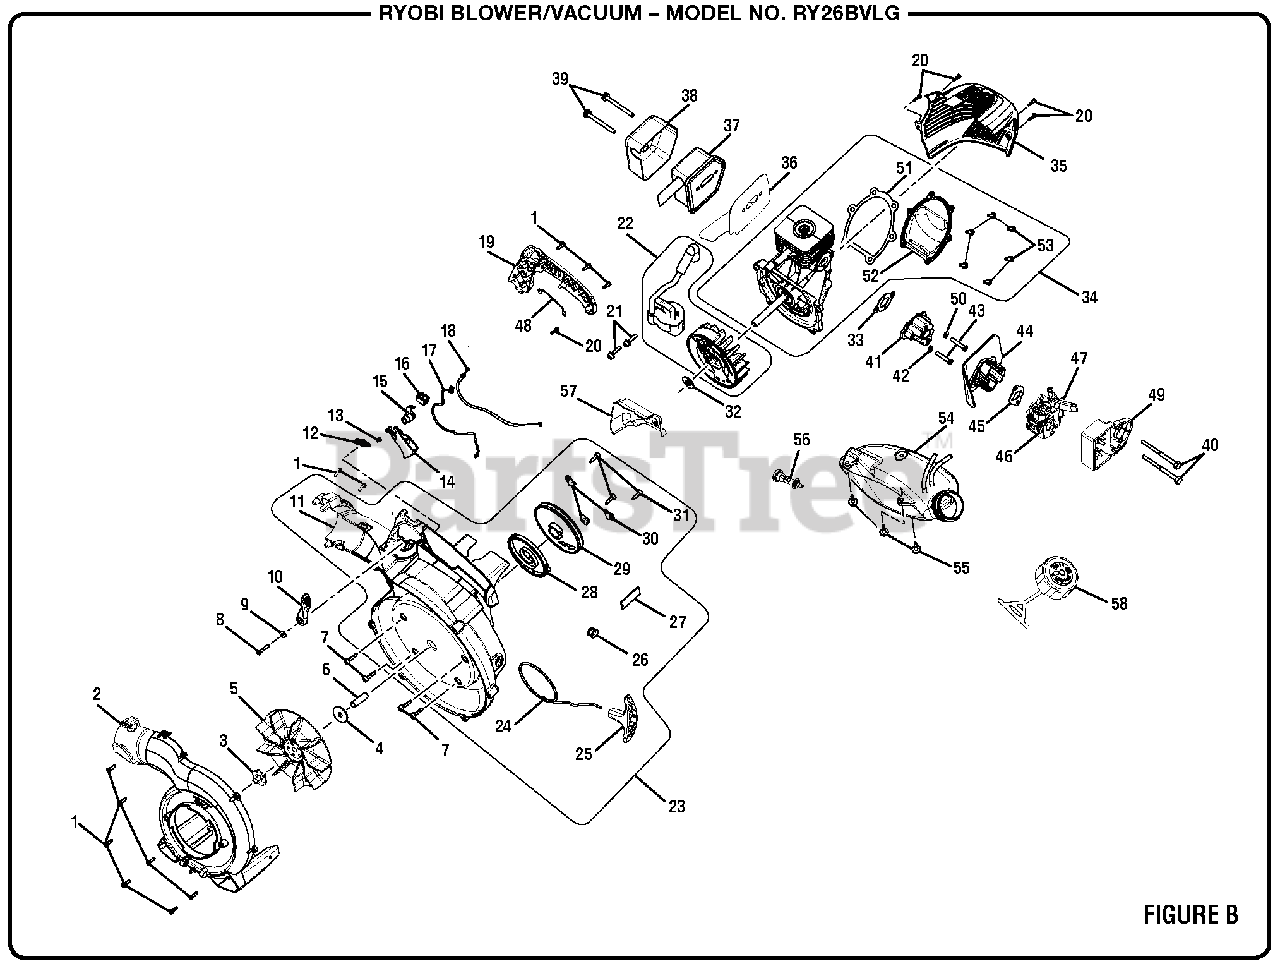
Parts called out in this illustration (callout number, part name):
1	Screw (10-14 x 3/4 in.)
2	Outer Volute w/Labels
3	Blower Fan Nut
7	Screw (M4 x 17 mm, T.F.)
8	Screw (8-14 x 1 in., T.F.)
10	Cruise Control Lever
11	Inner Volute w/Eyelet and Label
12	Throttle Lever
13	Screw (M3.5 x 7.5 mm)
14	Throttle Trigger
15	Trigger Lock
16	Momentary Contact Switch
17	Wire Assembly
18	Throttle Cable
19	Handle Cover
20	Screw (M4 x 18 mm)
21	Screw (M4 x 19 mm, T.F.)
22	Ignition Module and Flywheel Kit
23	Lower Housing w/Starter and Label
24	Starter Rope (42 in.)
25	Starter Grip
28	Spring & Container
29	Starter Pulley
30	Pulley Retainer
31	Screw (M4 x 14 mm, T.F.)
33	Intake Gasket
34	Short Block Assembly
35	Engine Cover w/Labels
36	Muffler Gasket
37	Muffler Assembly
38	Muffler Heat Shield
39	Screw (10-24 x 2-1/8 in.)
40	Screw (M5 x 48 mm)
43	Screw (M5 x 25 mm)
45	Heat Dam Gasket
46	Carburetor
47	Primer Bulb
48	Ground Wire Kit
49	Air Box Base
51	Crankcase Cover Gasket
52	Crankcase Cover
53	Screw (M4 x 12 mm)
54	Fuel Tank w/Fuel Lines
55	Screw (M4 x 14 mm, Shoulder)
56	Fuel Filter
57	Baffle Plate
58	Fuel Cap w/Tether
